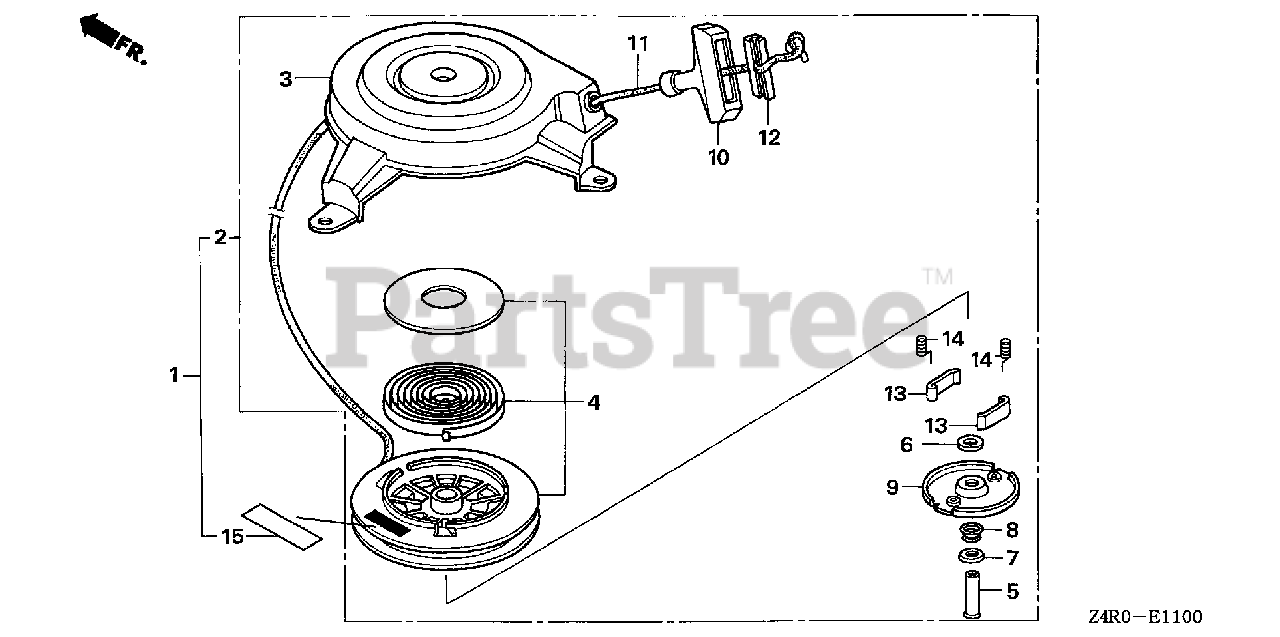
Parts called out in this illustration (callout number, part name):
2	STARTER ASSY., RECOIL
3	HOUSING ASSY. (NA USE ALT:28400-ZG9-803)
4	PULLEY & SPRING ASSY.
5	PIN, CENTER
6	PLATE A, FRICTION
7	PLATE B, FRICTION
8	SPRING, FRICTION
11	ROPE, RECOIL STARTER
12	HANDLE, REINFORCEMENT
14	SPRING, DOG
